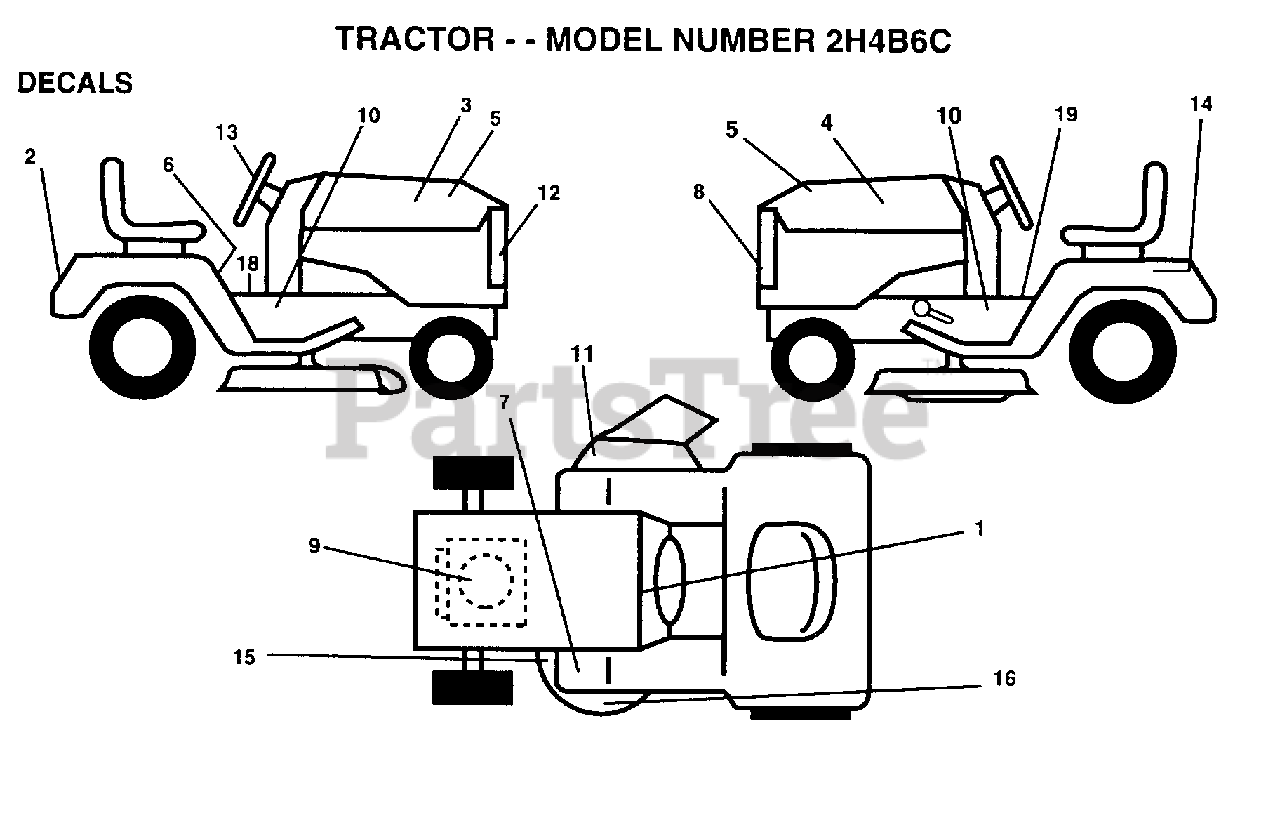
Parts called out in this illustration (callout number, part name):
1	DECAL.DASH.INSTR.
2	FENDER DECAL
3	DECAL HOOD RH RLY
4	DECAL HOOD LH RLY
6	DECAL CAUTION
7	DECAL T
9	DECAL, HP ENGINE
10	DECAL CHAS 42 HYD
11	"DECAL, WARNING"
12	GRILL DECAL
13	"DECAL,STR WHL"
14	DECAL.BTRY.DANGER
15	DECAL
18	DECAL SADL HYDRO
19	DECAL BRAK PARK
